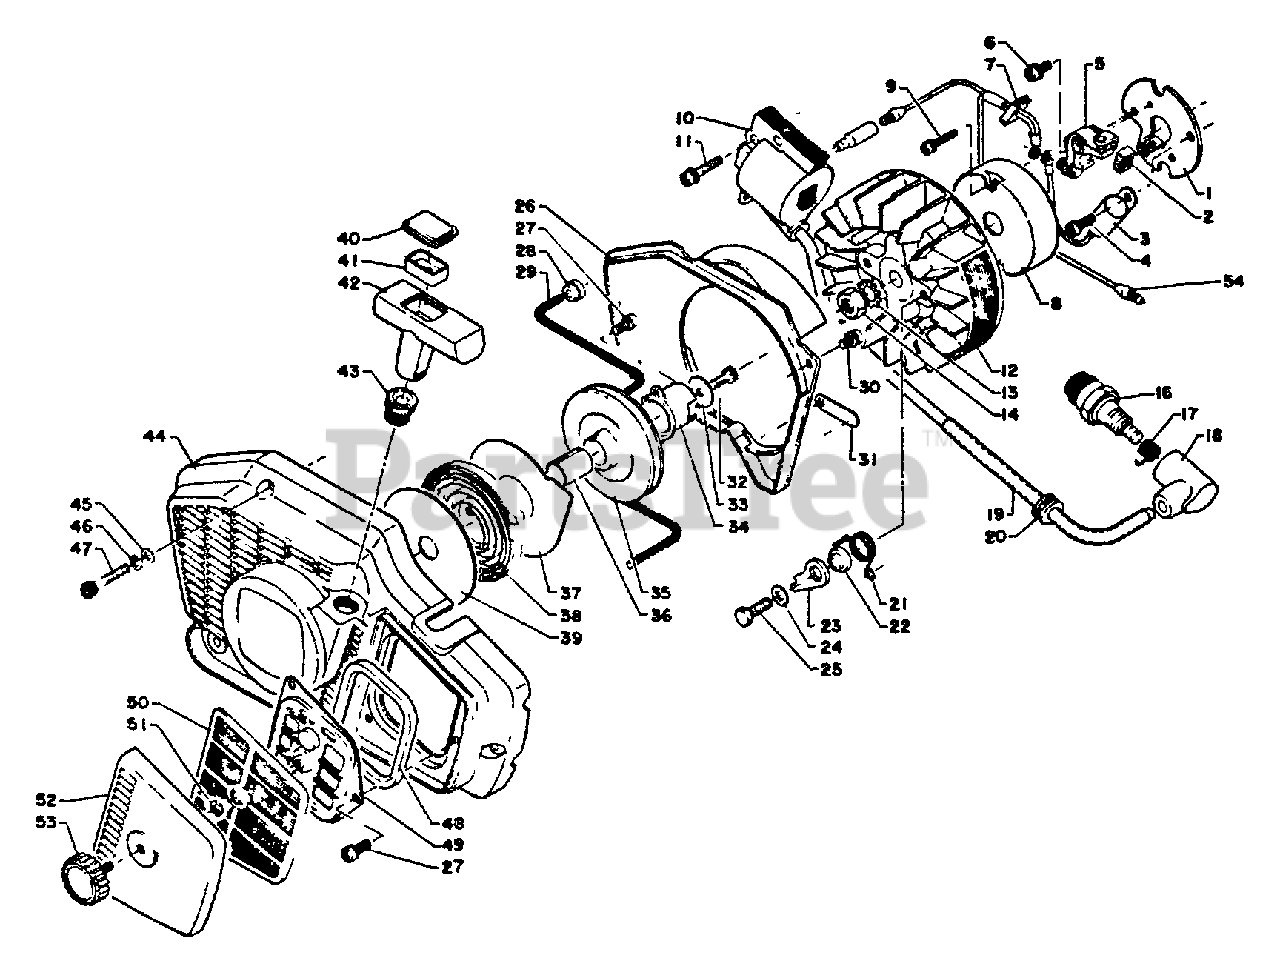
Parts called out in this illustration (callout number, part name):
1	STATER PLATE
2	OILER
3	CONDENSER
4	SCREW - 4×10
5	CONTACT POINT SET
6	SCREW 4×10
8	COVER, BREAKER
9	SCREW 3×25
10	COIL, IGNITION
11	SCREW 4×20
12	FLYWHEEL
16	SPARK PLUG - BM6A
16	SPARK PLUG - BMR6A
17	TERMINAL, SPARK PLUG
18	CAP, SPARK PLUG
19	TUBE
21	SPRING
23	PAWL, STARTER
24	WASHER 5.3×10×1
25	BOLT - 5×16
26	PLATE, GUIDE
27	SCREW 4×8
28	CLIP, STARTER ROPE
29	ROPE, STARTER 3.5×850
30	SCREW 4×8
31	GUIDE PLATE HOLDER
32	BOLT 4×14
33	WASHER 4.2×16.5×1
34	PAWL CATCHER
35	REEL, ROPE
36	BUSHING
37	PLATE, STARTER
38	SPRING, RECOIL
39	PLATE, SIDE
40	COVER, HANDLE
42	GRIP, STARTER
43	GUIDE, ROPE
44	CASE, STARTER
47	BOLT 4×25
48	GASKET, CARBURETOR CASE
49	PLATE
50	FILTER, AIR
51	E-RING 3
52	COVER, AIR FILTER
53	THUMBSCREW
54	LEAD
